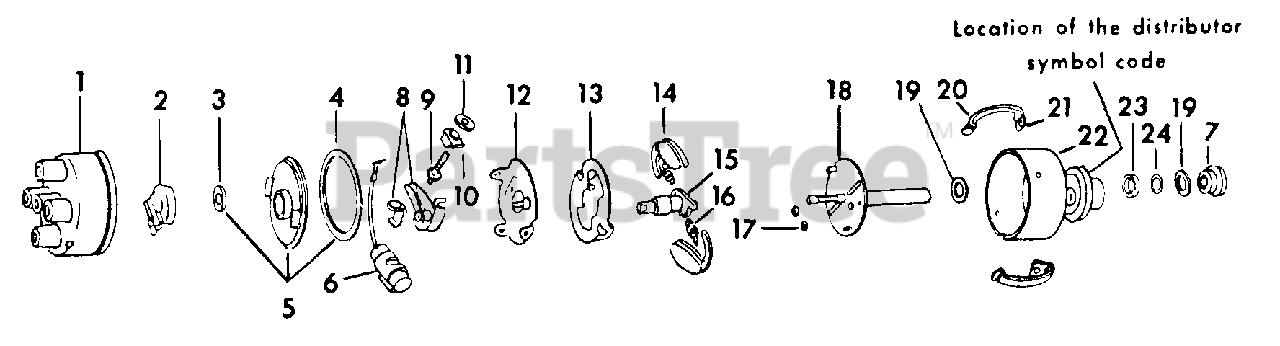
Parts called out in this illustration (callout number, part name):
1	CAP ASSY, DISTRIBUTOR
2	ROTOR ASSY, DISTRIBUTOR
3	FELT, BREAKER COVER SEAL
4	GASKET, BREAKER COVER
5	COVER ASSY, BREAKER
6	CONDENSER ASSY
7	GEAR, DISTRIBUTOR
8	PACKAGE, BREAKER POINT SET
9	SCREW, TERMINAL
10	INSULATOR, SPRING ANCHOR TERMINAL
11	WASHER, TERMINAL INSULATING
12	PLATE ASSY, BREAKER
13	GUARD, GOVERNOR WEIGHT
14	ARM ASSY, WEIGHT
15	CAM W/FELT, IH-355460-R1 ASSY
16	PACKAGE, GOVERNOR SPRING
17	SPACER, WEIGHT ARM
18	SHAFT ASSY, DISTRIBUTOR
19	WASHER, DISTRIBUTOR THRUST
20	SPRING, DISTRIBUTOR CAP
21	SUPPORT, DISTRIBUTOR CAP SPRING
22	HOUSING, DISTRIBUTOR W/SEAL
23	RETAINER, DISTRIBUTOR SHAFT OIL SEAL
24	O-RING, 1/2 X 11/16 X 3/32
